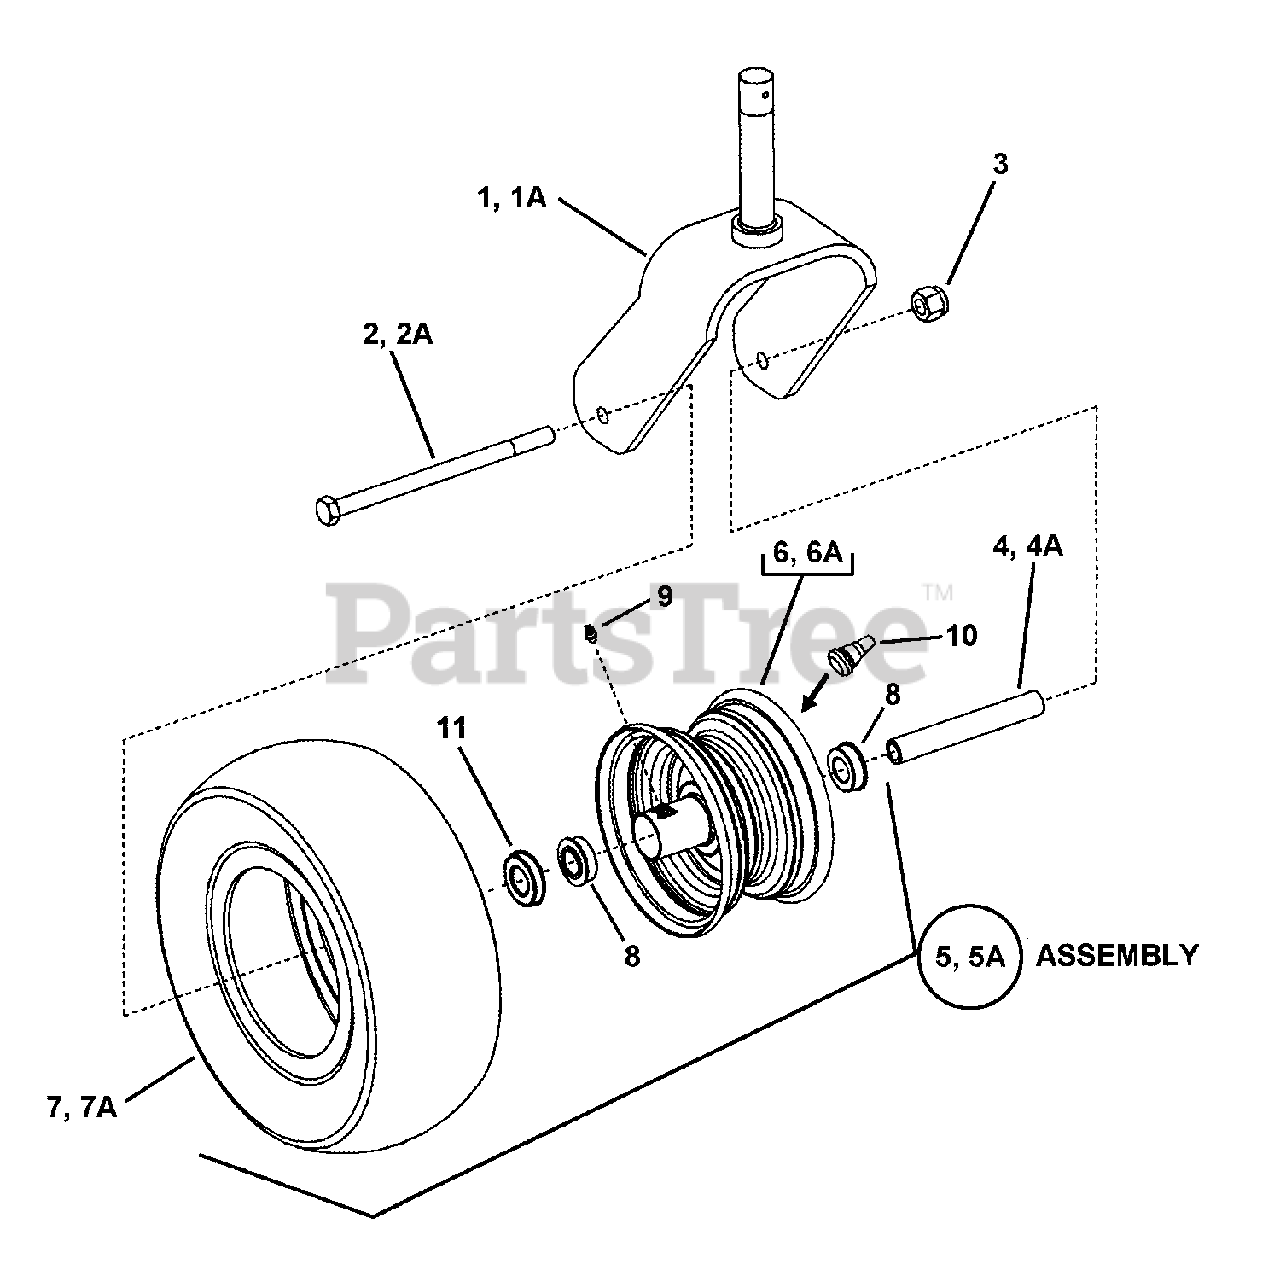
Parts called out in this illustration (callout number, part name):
1	WELDMENT, Caster Yoke
1A	WELDMENT, Caster Yoke, 7-1/4" Wide
2	BOLT, HEX, 1/2-13 X 7, GD 8, YZ
2A	SCREW, 1/2-13 x 9-1/2" Hex Head Cap, GR 5
3	NUT,1/2-13 Nyloc
4	SPACER, Bearing, 5.29" Long
4A	SPACER, Bearing, 7.29" Long
5	ASSY, Tire & Wheel (Incl. items 6, 7, 8, 9, 10 & 11)
5A	ASSY, Tire & Wheel (Incl. items 6A, 7A, 8, 9, 10 & 11)
6	WELDMENT, Wheel Hub & Rim (Grey)
6A	WELDMENT, Wheel Hub & Rim (Grey)
7	TIRE, 13 x 5.00-6 4 Ply Smooth TL
7A	TIRE, 13 x 6.5-6 4 Ply Smooth TL
8	BEARING, .750 Heim
9	FITTING, Lube
10	VALVE STEM, Air
11	SPACER
